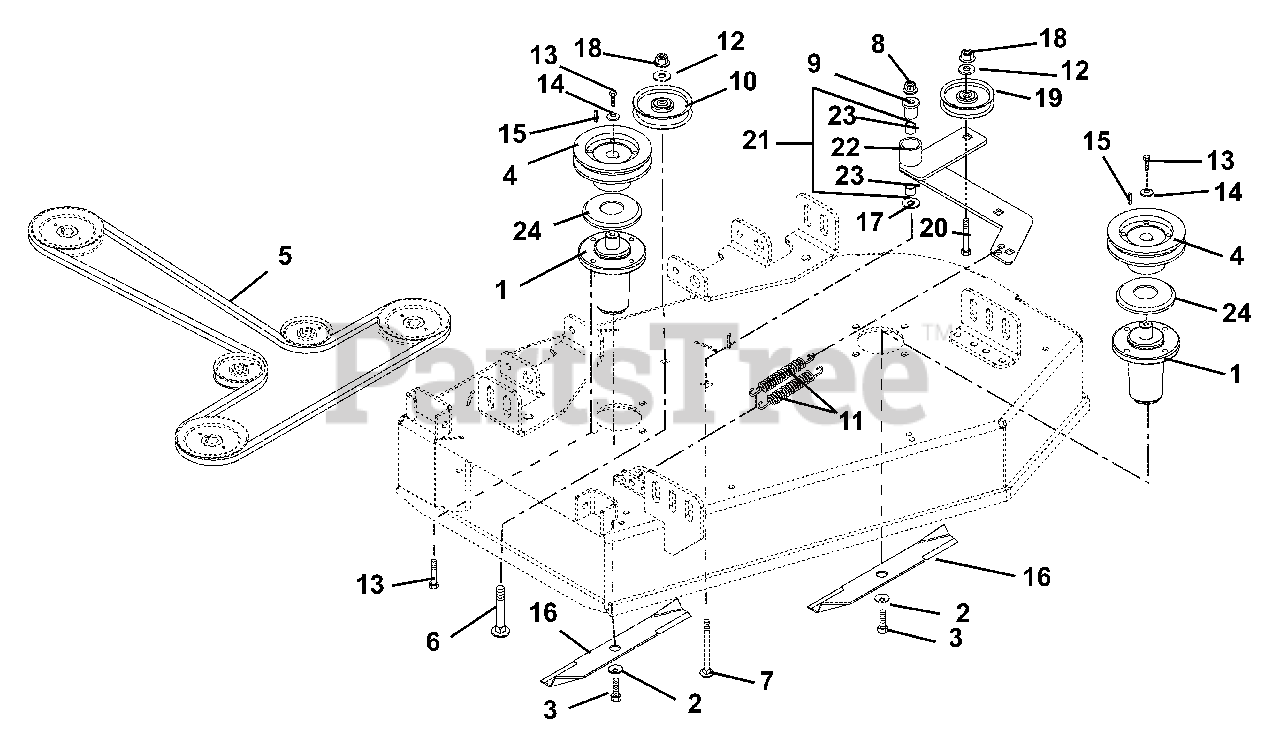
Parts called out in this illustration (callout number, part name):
1	Assembly, Maintenance Free Spindle
2	Washer-Bellville .63 x 1.625 x .14
3	Bolt-Hex .62-18 x 1.75 Grade 8
4	Sheave, 5.00 Spindle (1.00 I.D.)
5	V-Belt, B-Section 48.80 x .625
6	Bolt-Round Head Square Neck .38-16 x 2.75 Grade 5
7	Bolt-Round Head Square Neck .50-13 x 3.50 Grade 5
8	Nut-Locking-Top-Flange .50-13
9	Bearing, Pedestal Powdered Metal
10	Idler-Flat 4.00 x .38 (2.00 W)
11	Spring, Extension
12	Washer-Flat-Steel .375 x 1.125 x .065
13	Bolt-Hex .38-16 x 1.00 Grade 8
14	Washer-Flat-Steel .406 x 1.50 x .245
15	Key, Square .25 x .25 x 1.00
16	Blade, Mower Sand (314)
16	Blade, Mower Hi -Lift (056)
16	Blade, Mulching 50" Mower
17	Washer-Flat-Steel .563 x 1.38 x .109
18	Nut-Locking-Top-Flange .38-16
19	Idler, Flat 4.00 x .38 (1.00 W)
20	Bolt, Round Head Square Neck .38-16 x 2.00 Grade 5
21	Assembly, Idler Pivot Arm
22	Weldment, Idler Pivot Arm
23	Bearing, 1.00 x 1.12 x .75
24	Slinger-Dust
